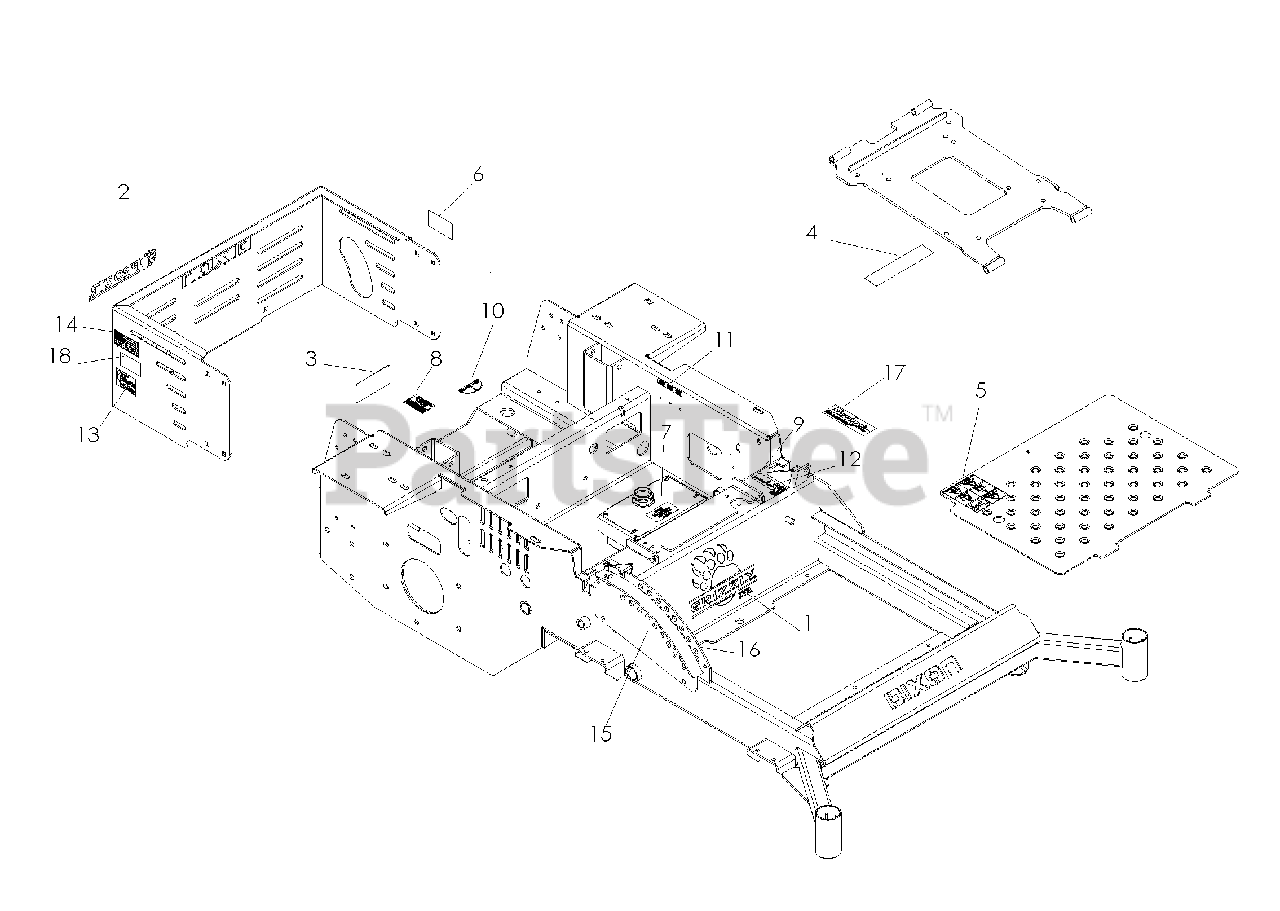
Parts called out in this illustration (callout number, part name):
1	DECAL, GRIZZLY
2	DECAL, PRO ZTR
3	DECAL, BELT DRIVE
4	DECAL, BATTERY
5	DECAL, WARNING
6	DECAL, PROP. 65
7	DECAL, OIL TANK
8	DECAL, EXHAUST
9	DECAL, MOTION CONTROL
10	DECAL, FUEL VALVE
11	DECAL, RELAYS
12	DECAL, F.S.T.
13	DECAL, PARKER
14	DECAL, FLAG
15	DECAL, HEIGHT
16	DECAL, HEIGHT
17	DECAL, FUSION
18	DECAL, KOHLER
